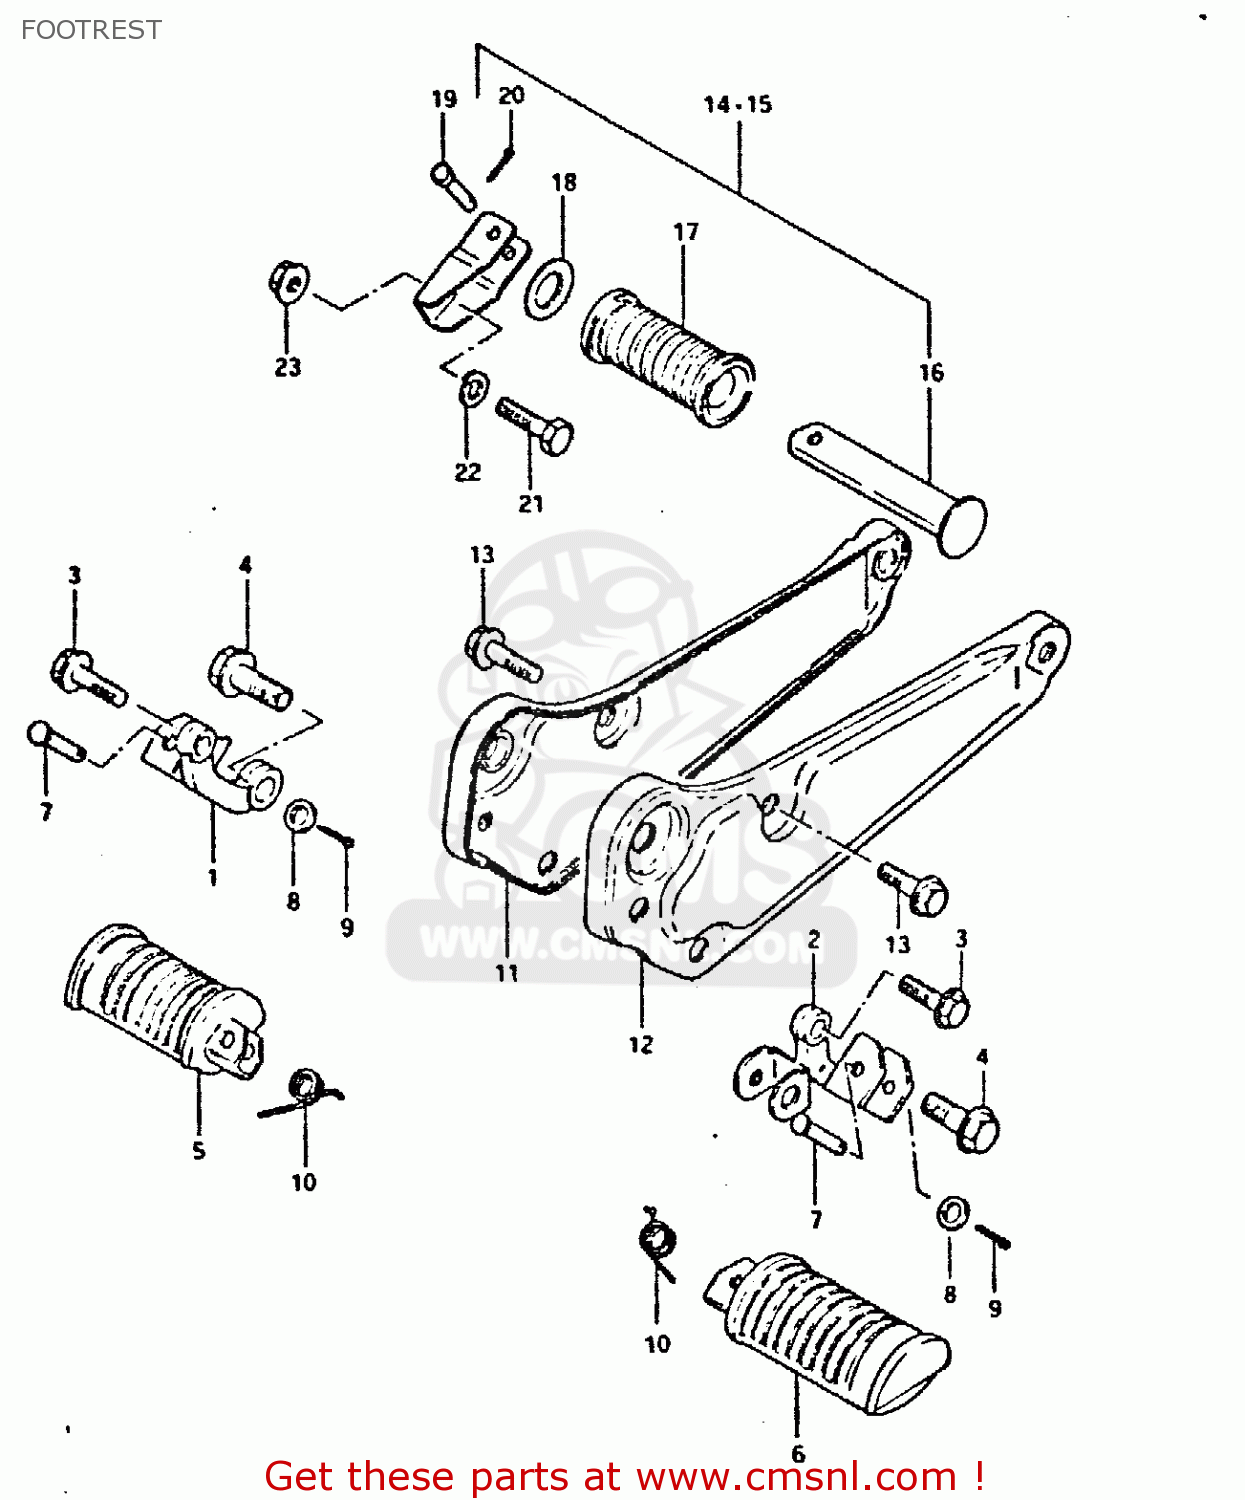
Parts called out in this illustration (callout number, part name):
1	BAR,FRONT FOOTREST,RIGHT
2	BAR,FRONT FOOTREST,LEFT
3	BOLT
4	BOLT
5	RUBBER,FRONT FOOTREST
6	FOOTREST
7	PIN
8	WASHER
9	PIN
10	SPRING
11	BRACKET
12	BRACKET
13	BOLT
14	FOOTREST ASSEMBLY,REAR
15	FOOTREST ASSEMBLY,PILLION
16	BAR,PILLION FOOTREST
17	RUBBER,PILLION FOOTREST
18	WASHER (19.5X32X2)
19	PIN
20	PIN
21	BOLT,M10X1.25X
22	LOCK WASHER
23	NUT
